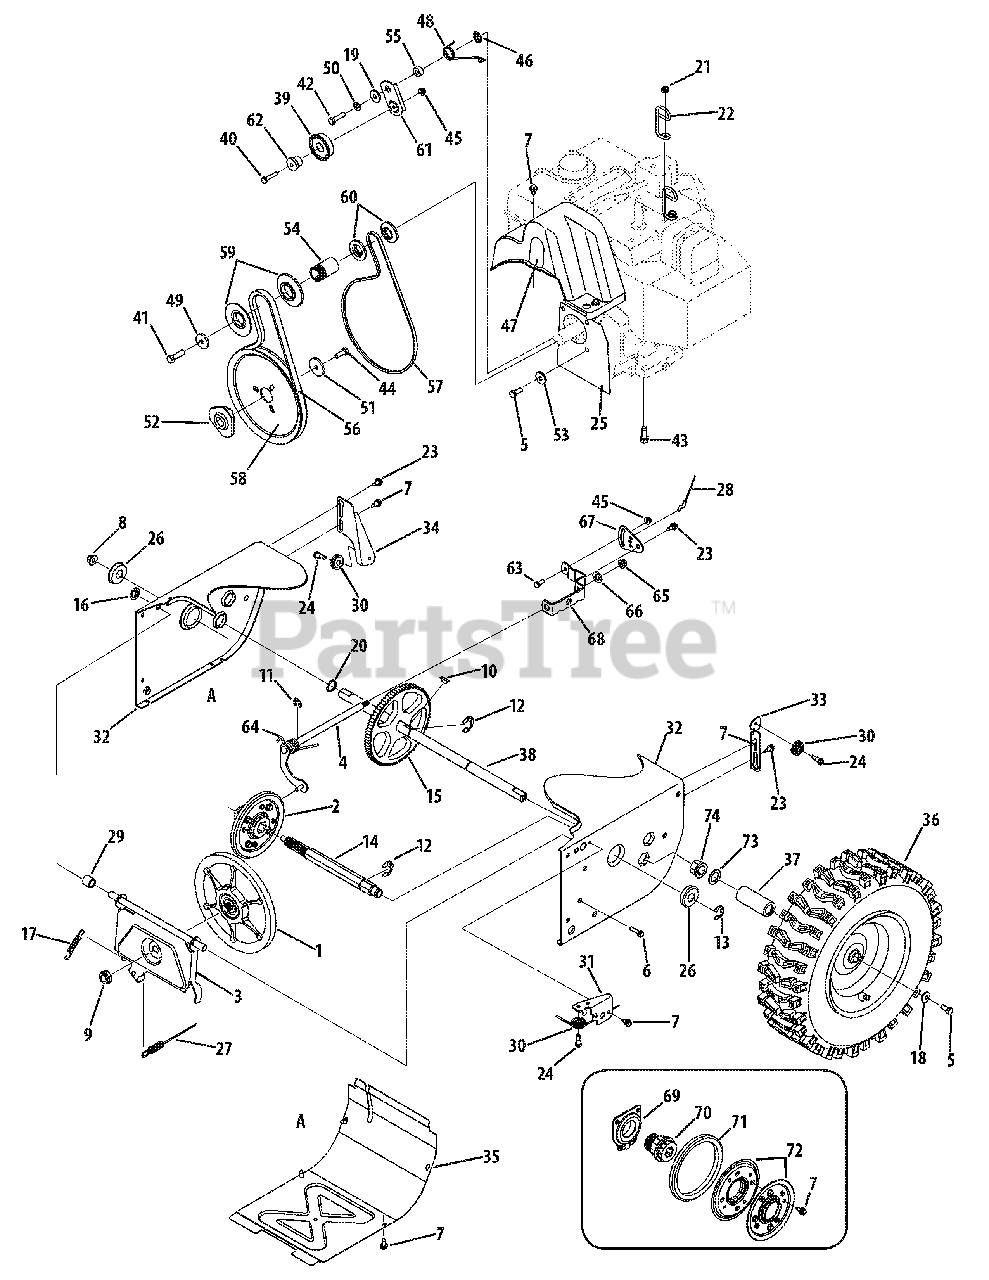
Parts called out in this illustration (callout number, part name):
1	Disc Assembly, Friction Wheel
2	Friction Wheel Assembly, 5.5 OD
4	Shift Assembly, Rod
5	Hex Screw, 5/16-24, .750, Gr5
6	Screw, 1/4-20, 1.000
7	Screw, 1/4-20 x .625
8	Nut, Flange Lock, 3/8-16, Nylon
9	Jam Lock Nut
10	Hi-pro Key
11	E-Ring, .500 Dia
12	E-Ring, .875 Dia
13	E-Ring, .750 Dia
14	Hex Shaft, .8125
15	Gear
16	Speed Nut, .500
17	Extension Spring
18	Bell Washer, .340 x .872 x .060
19	Shoulder Spacer
20	Flat Washer, .75 x 1.00 x .060
21	TT Screw, 5/16-18 x 1.00
22	Cable Guide
23	Shoulder Screw, .37 x .105, 1/4-20
24	Screw, 1/4-28, .375
26	Ball Bearing, 17 x 40 x 12
27	Wheel Clutch Cable, 44.95''
28	Speed Selector Cable
29	Spacer, .508 ID x .75 OD x 68
30	Cable Roller
37	Spacer, 1.25 x .75 x 3.0
38	Axle, .75 x 22''
39	Ball Bearing
40	Hex Screw, 1/4-20, 1.25
41	Hex Screw, 3/8-24, 1.25
42	Hex Screw, 5/16-24, 1.253
43	Sem Screw, 3/8-16, 1.11
44	Hex Screw, 5/16-24, .875, Gr8
45	Flange Lock nut, 1/4-20, Nylon
46	Push-on Nut, .25 Dia
47	Belt Cover
48	Torsion Spring, .850 ID x .354
49	Flat Washer, .406 x 1.25 x .157
50	Lock Washer, .3125
51	Flat Washer, .34 x 1.50 x .150
52	Adapter Pulley, .75 Dia
53	Shoulder Spacer, .317 x .50 x .102
54	Spacer, .875 ID x 1.185 OD
55	Spacer, .340 x .750 x .360
56	Auger Drive Belt, .500 x 35
57	Wheel Drive Belt, 3/8 x 34.4
58	Auger Drive Pulley, 8.1 x .5
59	Pulley Half, V x 2.600 OD
60	Pulley Half, 1/4-V x 1.5 OD
61	Wheel Drive Idler Bracket
62	Shoulder Spacer, .26 x .79 x .538
63	Hex Screw, 1/4-20, .620
64	Torsion Spring, .750 ID x .968
65	Flange Lock Nut, 5/16-18, Nylon
66	Shift Spacer Bracket
69	Bearing Assembly
70	Friction Wheel Hub
71	Friction Wheel rubber
72	Friction Wheel Plate
73	Flat Washer
74	Hex Flange Bearing
